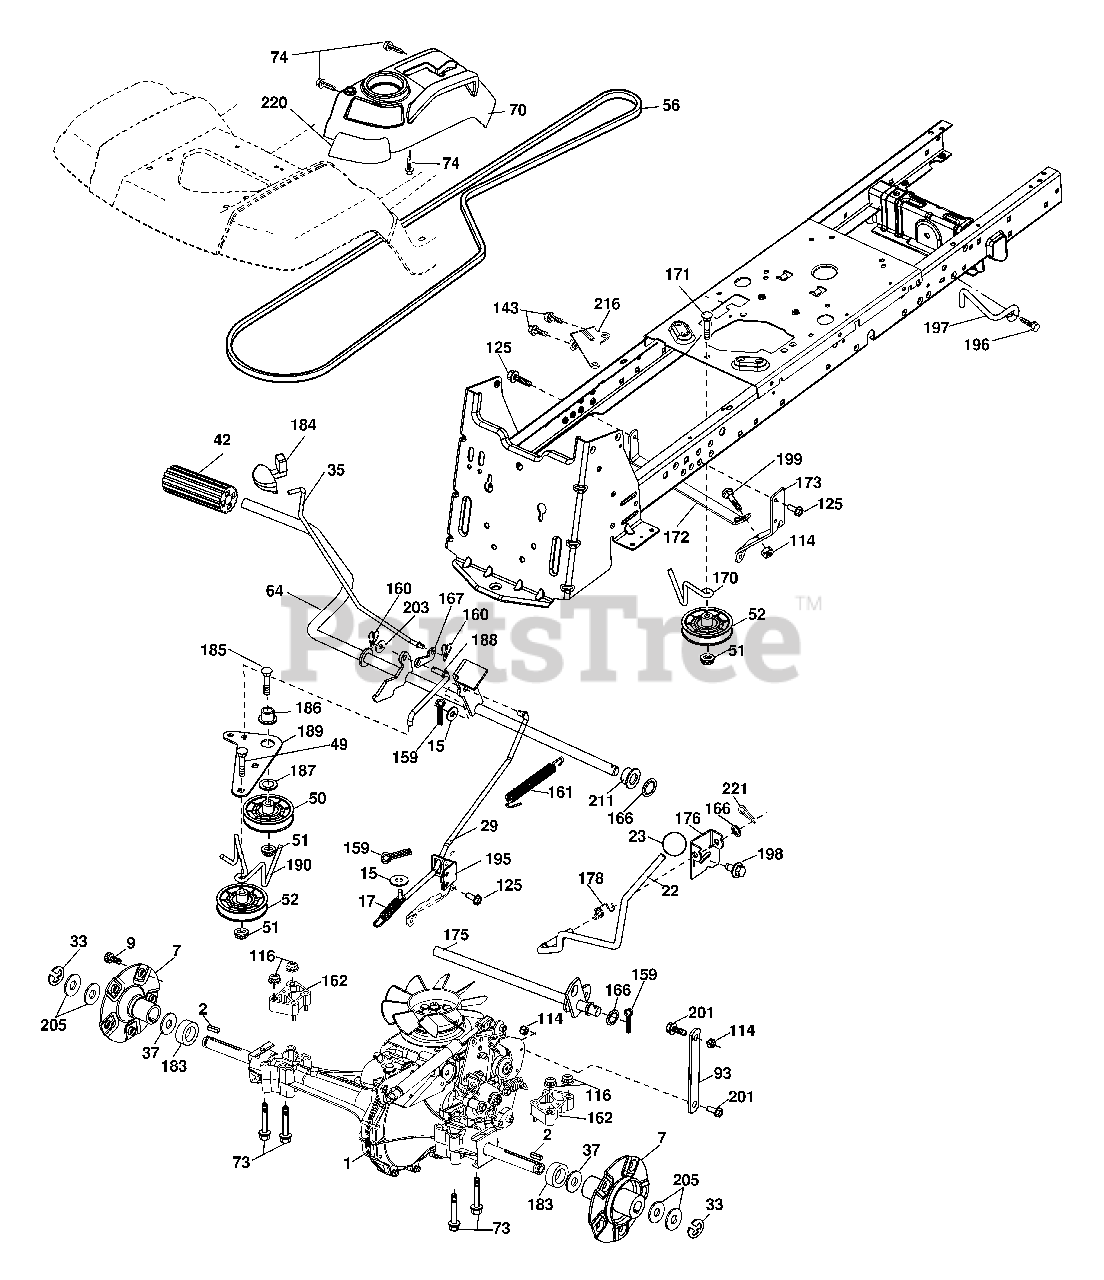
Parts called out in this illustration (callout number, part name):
2	Key 1/4 x 2.5
7	Hub Asm. Wheel
9	Bolt Hub Wheel
15	Washer 13/32 x 13/16 x 16 Ga.
17	Spring, Brake
22	Shifter Rod
29	Rod, Brake
35	Rod, Brake, Park
42	Cover, Foot Pedal
50	Pulley Idler Flat
51	Lock Nut 3/8-16
52	Idler V-Groove 910" Offset
56	V-Belt, Drive
64	Shaft Asm. Pedal Brake Control
70	Control Asm.
73	Bolt Hex Flghd 5/16-18 x 3.75
74	Screw 1/4 x 1/2
93	Link Shift
114	Nut Lock Hex w/Insert 5/16-18 unc
116	Nut Lock Hex Flange 5/16-18
125	Screw 5/16-18 x 3/4
143	Screw Thdrol 5/16-18 x 1/2
159	Pin Cotter 1/8 x 3/4
160	Retainer Clip
161	Spring, Return, Clutch
162	Spacer Trans.
166	Nut Push .625
167	Latch Brake Parking
170	Keeper Belt Centerspan
172	Strap Torque LH
173	Strap Torque RH
175	Shaft Asm Shift
176	Arm, Shift Rod
178	Spring Shift
183	Spacer Split
184	Handle Parking Brake
185	Bolt Rdhd Sqnk 3/8-16 x 2-1/2
186	Spacer Retainer
187	Washer
188	Link Clutch Ground Drive
189	Bellcrank Ground Drive
190	Keeper Bellcrank Ground Dr.
195	Bracket Rod Brake
196	Screw 3/8-16 x 1
197	Bracket Clutch Anti-Rotation
198	Screw 7/16-14 x 7/8 Flghd
199	Bolt Rdhd Sqnk 5/16-18 unc x 1
201	Bolt Shoulder 5/16-18 unc
203	Washer 11/32 x 11/16 x 16 Ga.
216	Bracket Pulley Idler
220	Reflector RH
221	Retainer Spring Clip Handle
